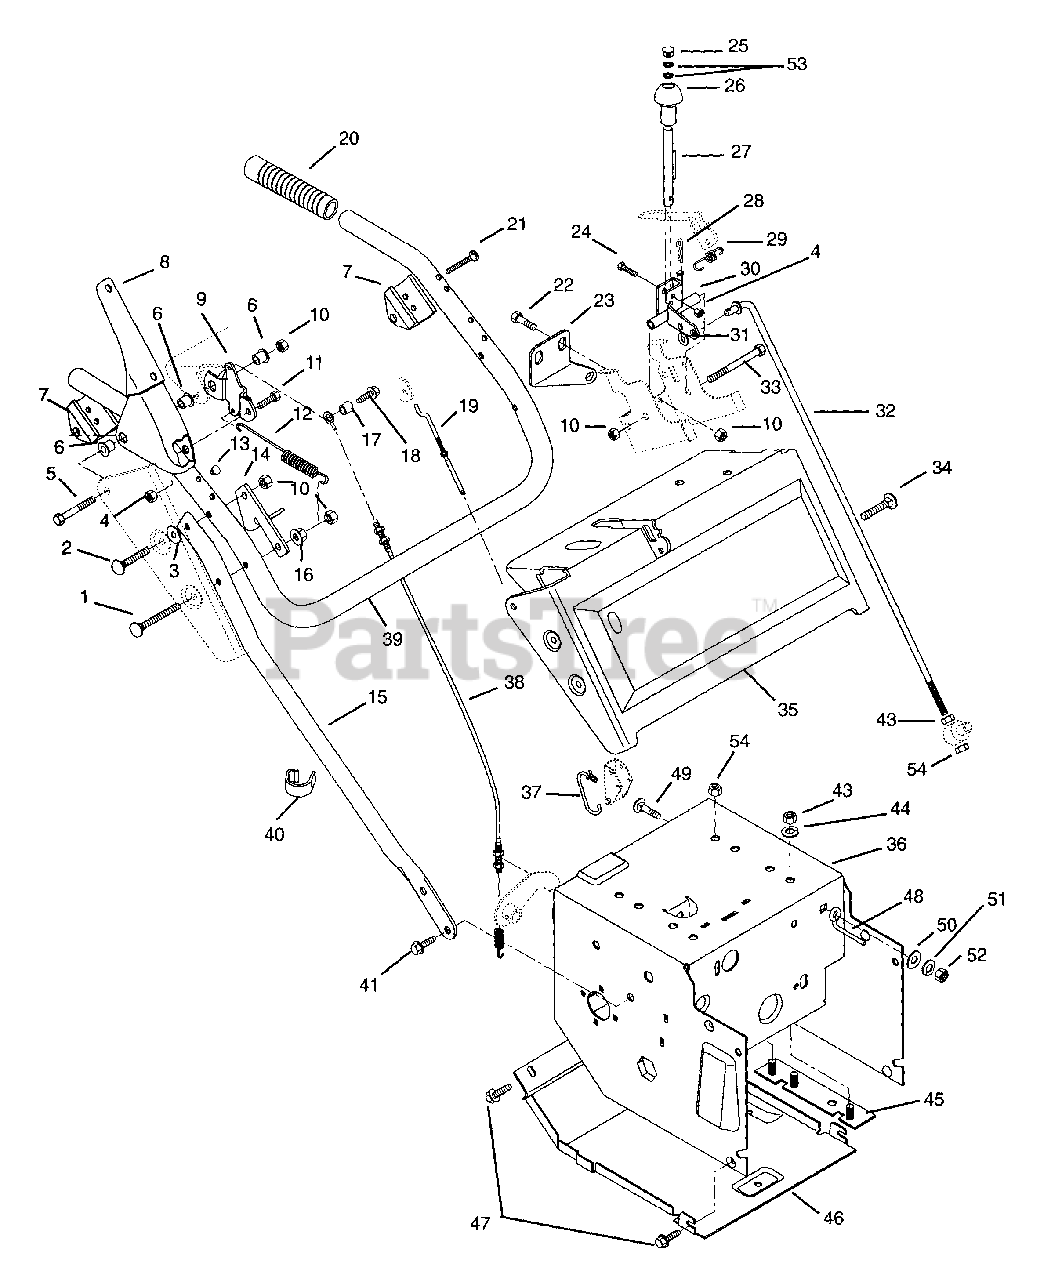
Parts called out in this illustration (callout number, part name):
1	BLT-RDHDSQSHNK.31-18X2.75G2YWZ
2	@BLT-RDHDSQNK .31-18X1.50 G5YZ
3	@WSHR-FL-STL.438X1.00X.083 YWZ
4	@NUT-LK-CTR .25-20 YWZC
5	@BLT-HEX .31-18X2.50 GR5 YWZC
6	BSHG-FLG .325X.465X.333X.685
7	HANDLE PIVOT
8	CLUTCH LEVER - COATED
10	@NUT-LK-CTR .31-18 YWZC
11	BLT-HEX .25-20X.38 YWZC GR5
12	SG-TENS .051X.50X5.12 WLD 10.4
14	UPPER CABLE ANCHOR R H
15	L H LOWER HANDLEBAR
16	@NUT-SPNLK-FLG .312-18 YWZC
17	SPACER .230X.310X.255
18	@SCR-TAP 12-24X.50 HWH TR YWZC
19	CABLE, ADJUSTABLE
20	HANDLE GRIP
21	SCR-TAP 12-24X1.50 CROVH YZ BT
22	@BLT-HEX .31-18X.50 GR5 YWZC
23	CHUTE CRANK BRACKET
24	@BLT-HEX .25-20X1.00 GR5 YWZC
25	HOLE PLUG
27	ROD
28	PIN-HAIR INT .08X.18X1.18 YWZC
29	SG-TENS .055X.33X1.31 WLD 7
31	@WSHR-FL-STL.406X.812X.065 YWZ
32	SHIFT ROD
33	@BLT-HEX .31-18X3.50 GR5 YWZC
34	BLT-RDHDSQSHK .31-18X1.75 YWZC
35	PANEL W/DECAL
38	CLUTCH CABLE-ATTACHMENT
39	UPPER HANDLEBAR
41	BLT-SERHFWH .312-18X.625 YWZC
43	@NUT-HEX .31-18 YWZC
44	WSHR-LK .312X.097 HVY YWZC
45	ENGINE MOUNT, 5L,7L,8R
46	COVER BOTTOM
47	@SCR-TAP .25-20X.37 HWH YWZ TR
48	BELT FINGER LOWER
49	@BLT-RDHDSQNK .31-18X1.00 G5YZ
50	@WSHR-FL-STL.38X.875X.083 YWZC
51	@WSHR-LK .31X.078 REG YWZC
52	@NUT-HEX .31-18 YWZC
53	RG-RTNG-EXT .500X.015
54	@NUT-LK-NYL .312-18 YWZC
